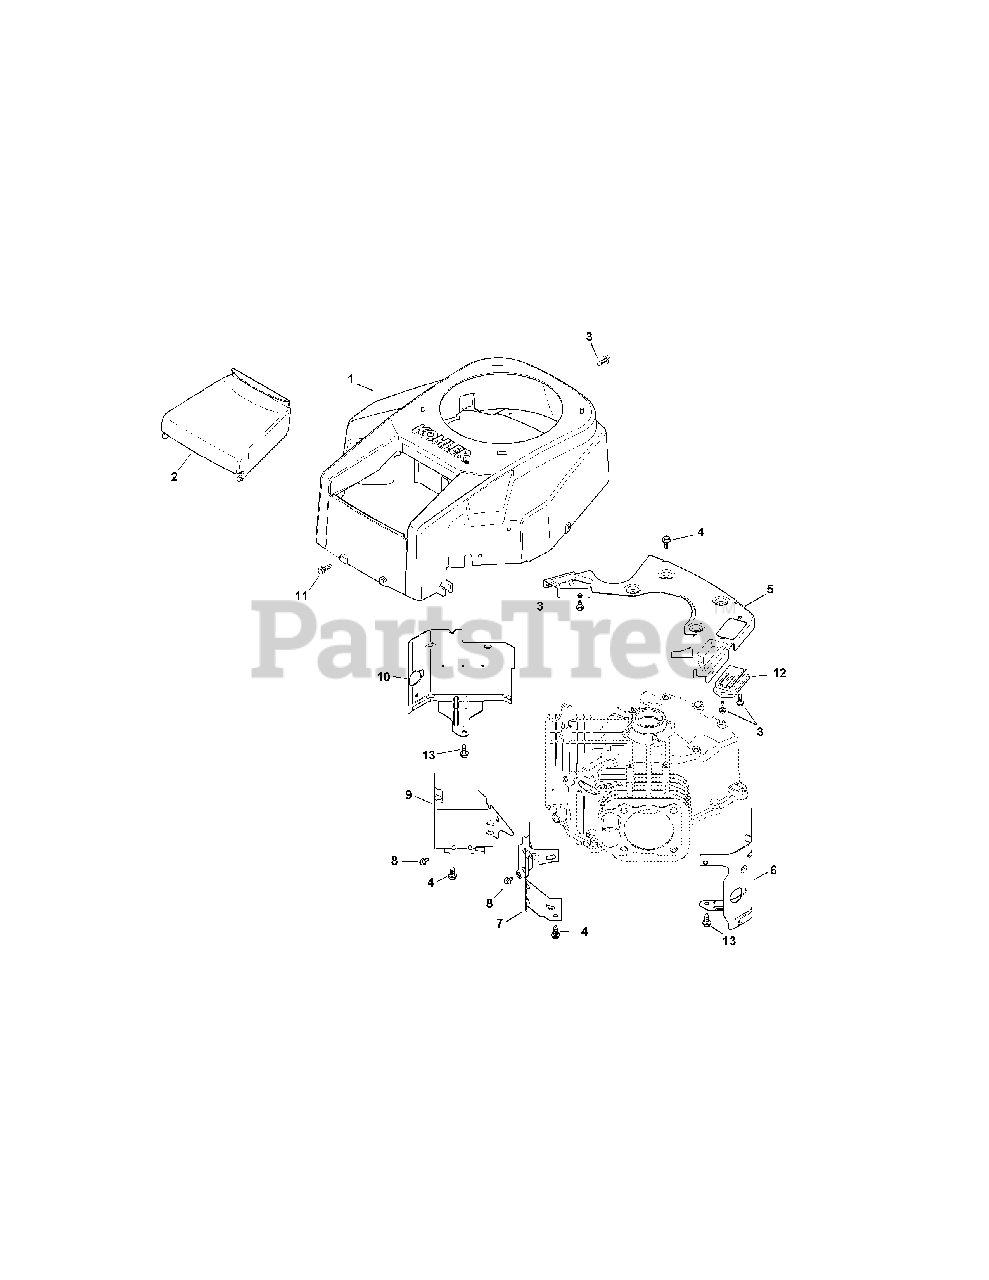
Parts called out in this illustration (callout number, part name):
1	Blower Housing Kit (Fixed Guard)
2	Air Cleaner Cover
3	Flange Screw, M5 x .8 x 16
4	Flange Screw, M6 x 1.0 x 16
5	Backing Plate Kit
6	Cylinder Barrel Baffle, #2 Side
7	Valley Baffle, #2 Cylinder
8	Flange Screw, M5 x .8 x 10
9	Valley Baffle, #1 Cylinder
10	Cylinder Barrel Baffle, #1 Side
11	Tap Screw, M6 x 1.7 x 18
12	Regulator/Rectifier
13	Screw, M6 x 1.0 x 10
